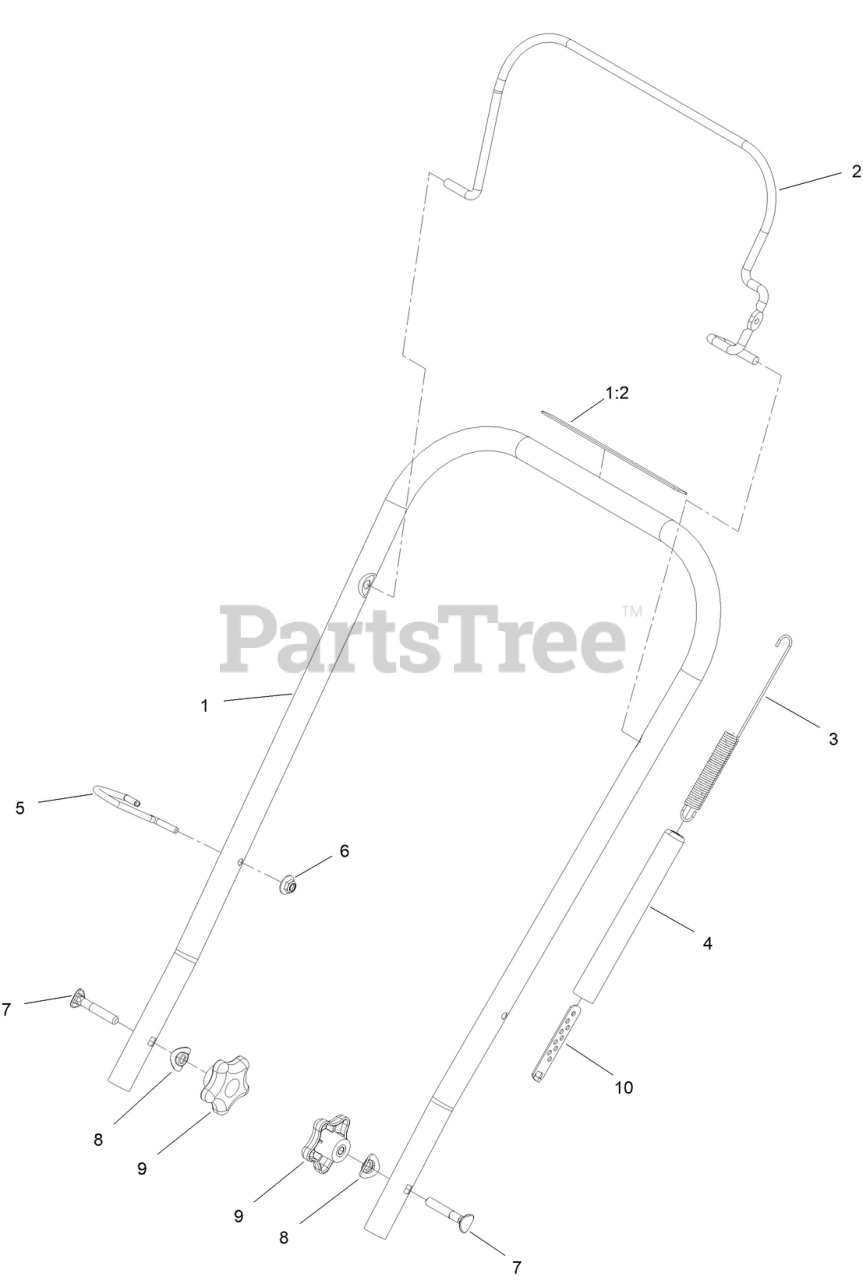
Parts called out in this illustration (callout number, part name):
1	UPPER HANDLE ASM
1:2	DECAL-SAFETY
2	BAIL-CLUTCH
3	SPRING-CLUTCH
4	COVER-SPRING
5	GUIDE-ROPE
6	NUT-HF
7	SCREW-HANDLE
8	WASHER-CUP
9	KNOB-HANDLE
10	ADJUSTER-CLUTCH CABLE
